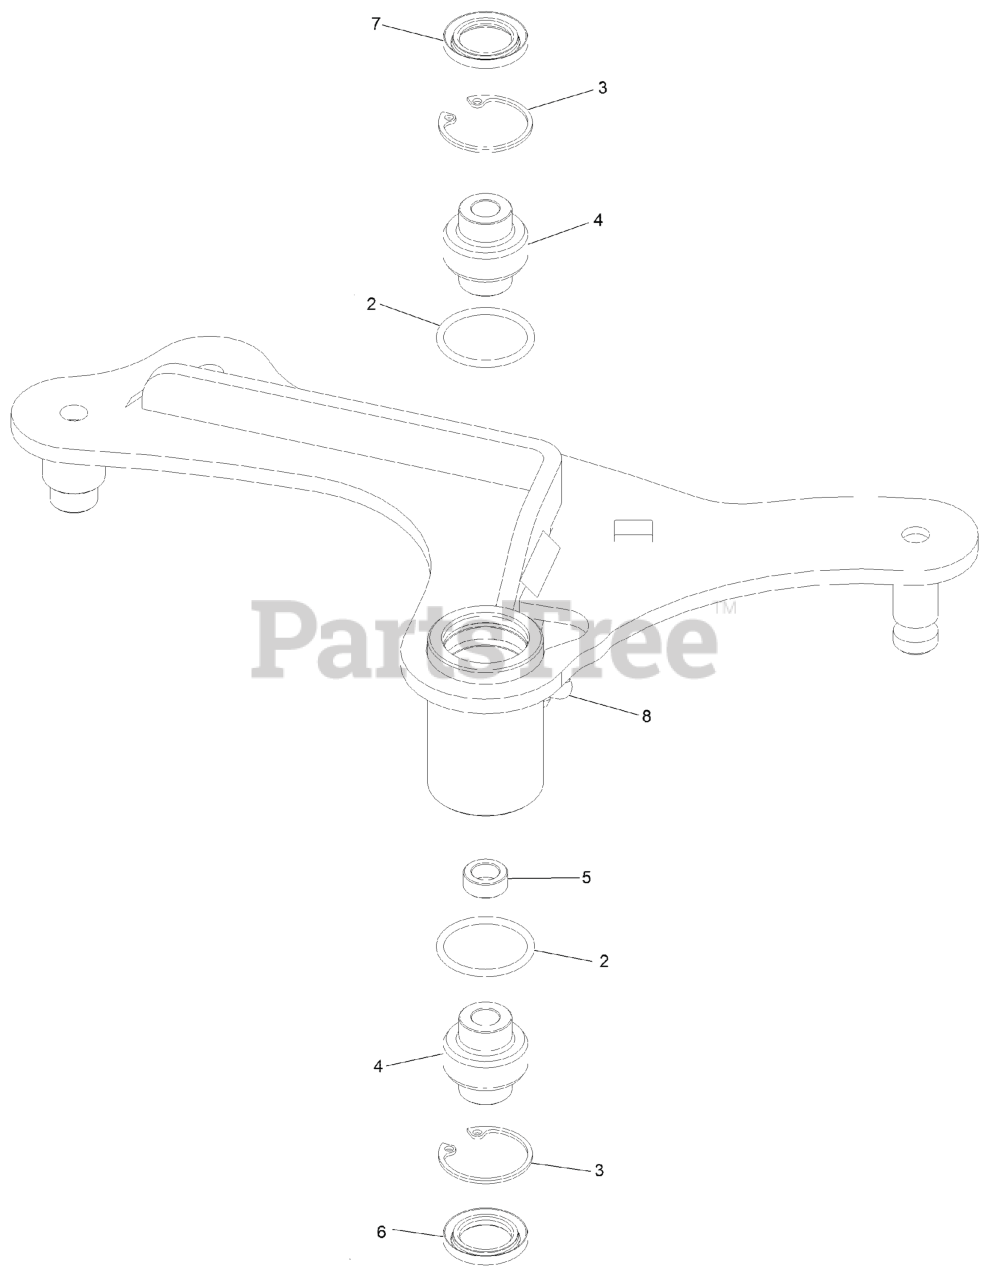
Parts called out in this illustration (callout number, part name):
3	RING-SNAP
4	BEARING-SPHERICAL
6	SEAL-LIP, DOUBLE
7	SEAL-LIP, SINGLE
8	FITTING-GREASE, 90 DEG
